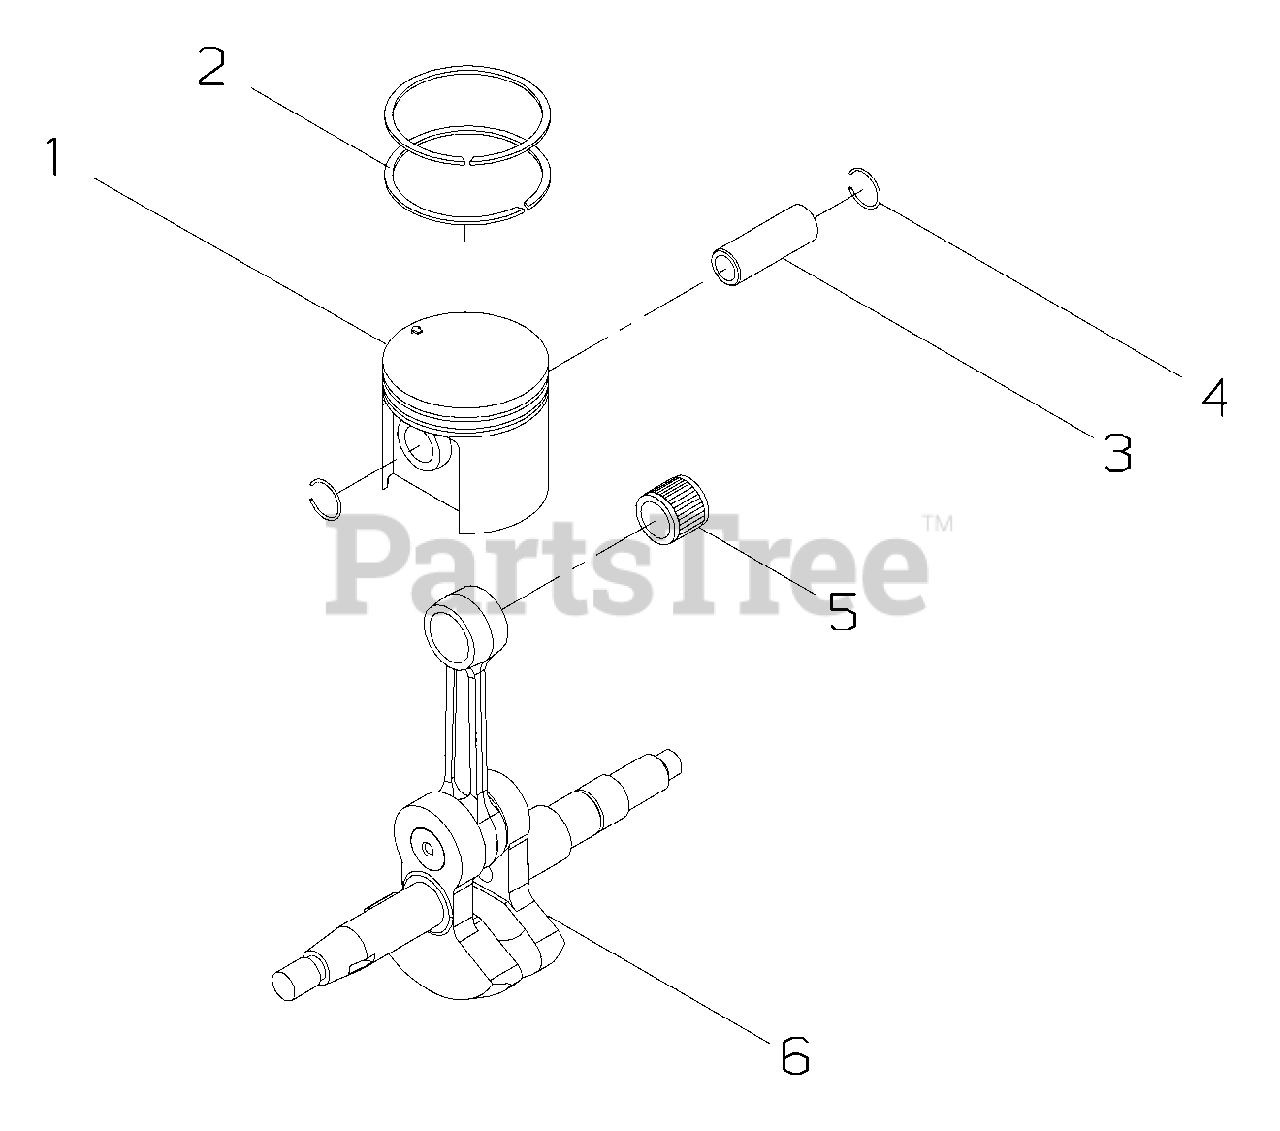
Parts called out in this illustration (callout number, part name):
1	PISTON
2	RING, PISTON
3	PIN, PISTON
4	RING, RETAINING
5	BEARING, NEEDLE
6	CRANKSHAFT ASSY
